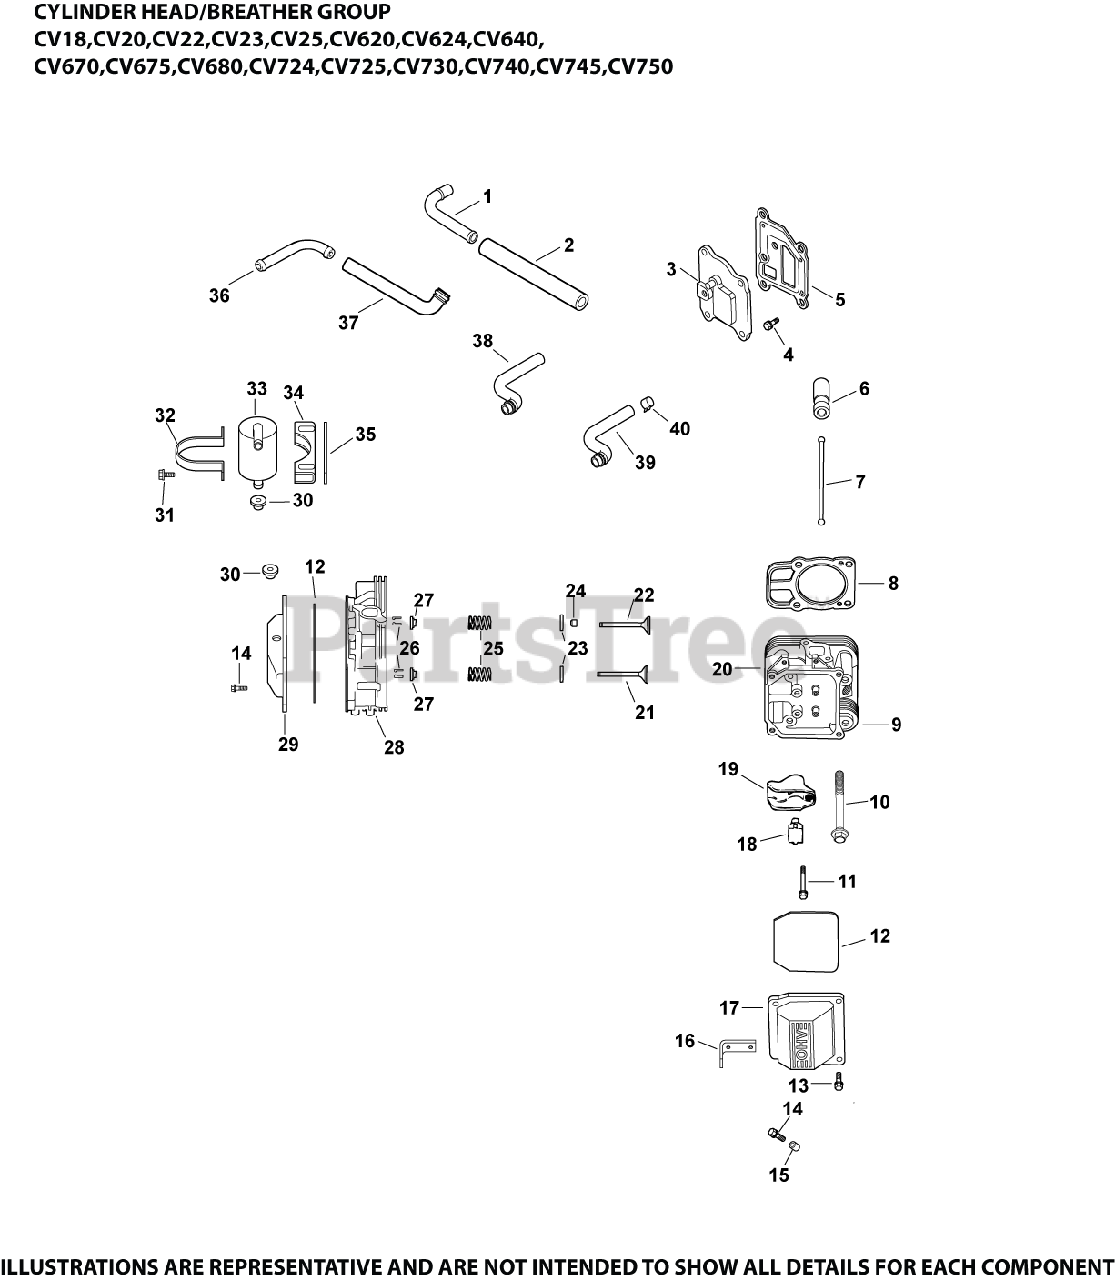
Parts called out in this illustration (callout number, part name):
2	HOSE, BREATHER-USE 24 326 93-S
3	KIT, BREATHER COVER W/GASKET
3	COVER, BREATHER -USE 24 096 125-S
4	SCREW,FLG THD FRM M6X1.0X20-(#25086396S)
5	GASKET, BREATHER-USE 24 041 67-S
6	LIFTER, HYDRAULIC VALVE-USE 25 351 10-S
7	ROD, PUSH
8	CYL HEAD GASKET KIT-USE 24 841 04-S
9	HEAD, ASSEM CYLINDER #2 -USE 24 318 116-
11	SCREW, ROCKER ARM PIVOT-USE M-640034-S
12	O-RING (YELLOW) -USE 24 153 30-S
14	SCREW, FLG M6X1.0X30
16	STRAP, LIFTING-USE 25 445 03-S
17	KIT, VALVE COVER-PLAIN
18	PIVOT, CYLINDRICAL ROCKER ARM-USE 24 599
19	ARM, ROCKER
20	KIT, VALVE TRAIN
21	VALVE, EXHAUST (STD) - USE 32 016 01-S
21	VALVE, EXHAUST (.25)
22	VALVE, INTAKE (STD)
22	VALVE, INTAKE (.25)
23	RETAINER, SPRING
24	SEAL, VALVE STEM - (#2503214S)
25	SPRING, VALVE
26	KIT, RETAINER
27	RETAINER, VALVE SPRING - USE 25 173 28-S
28	HEAD, ASSEM CYLINDER #1 -USE 24 318 108-
29	KIT, VALVE COVER
30	GROMMET, RUBBER
31	SCREW,FLG THD FRM M5X0.8X16-(#25086398S)
32	STRAP, BREATHER - USE 24 755 241-S
33	KIT, BREATHR SEPARATR-(#24755241S)
34	BRACKET, BREATHER SEPARATOR
35	SPACER
36	FITTING
37	HOSE, BREATHER-USE 24 326 86-S
38	HOSE, BREATHER-USE 24 326 87-S
